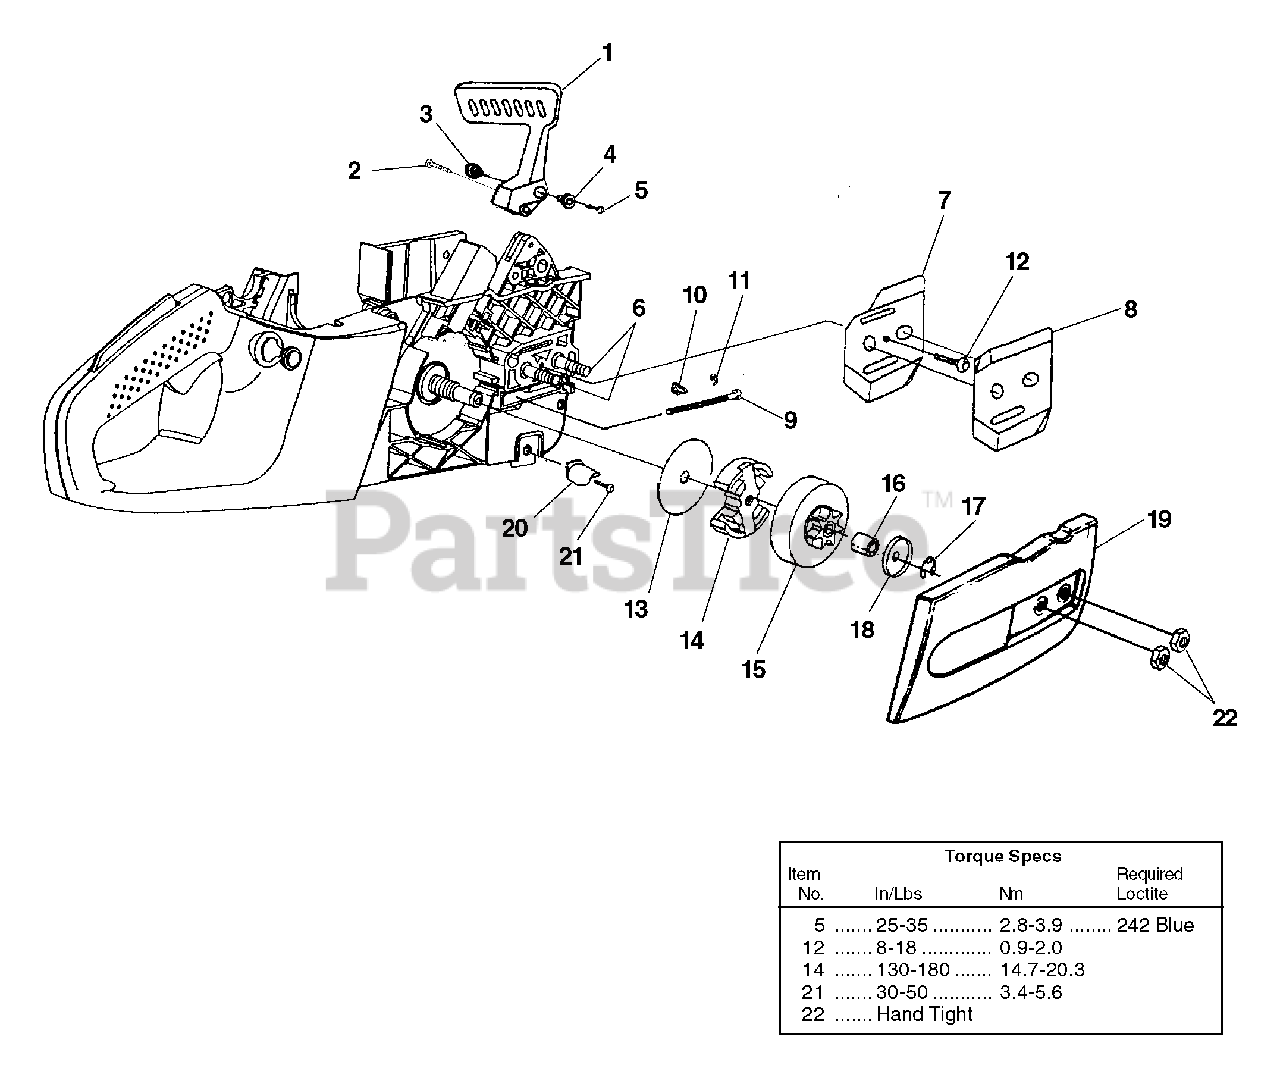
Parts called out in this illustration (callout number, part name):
1	Hand Guard Kit
2	Screw-Thd. form. (#8-14 x .625)
3	Pivot, L.H.
4	Pivot, R.H.
5	Screw, Hex Socket Hd. (8-32 x 5/8")
6	Guide Bar Bolt
7	Plate, Guide Bar
8	Plate, Guide Bar
9	Screw, Guide Bar Adjusting
10	Pin, Guide Bar Adjusting
11	Ring, Retaining
12	Screw, Thread Form., Plastite (6-19 x 1/2")
13	Thrust Washer
14	Clutch & Hardware
15	Sprocket, Drum (3/8 Pitch)
16	Bearing, Needle
17	Ring, Retaining
18	Washer, Cupped
19	Drive Case Cover
20	Stop, Chain
21	Screw, Thread Form., Plastite (10-14 x 3/4")
22	Nut, Hex
